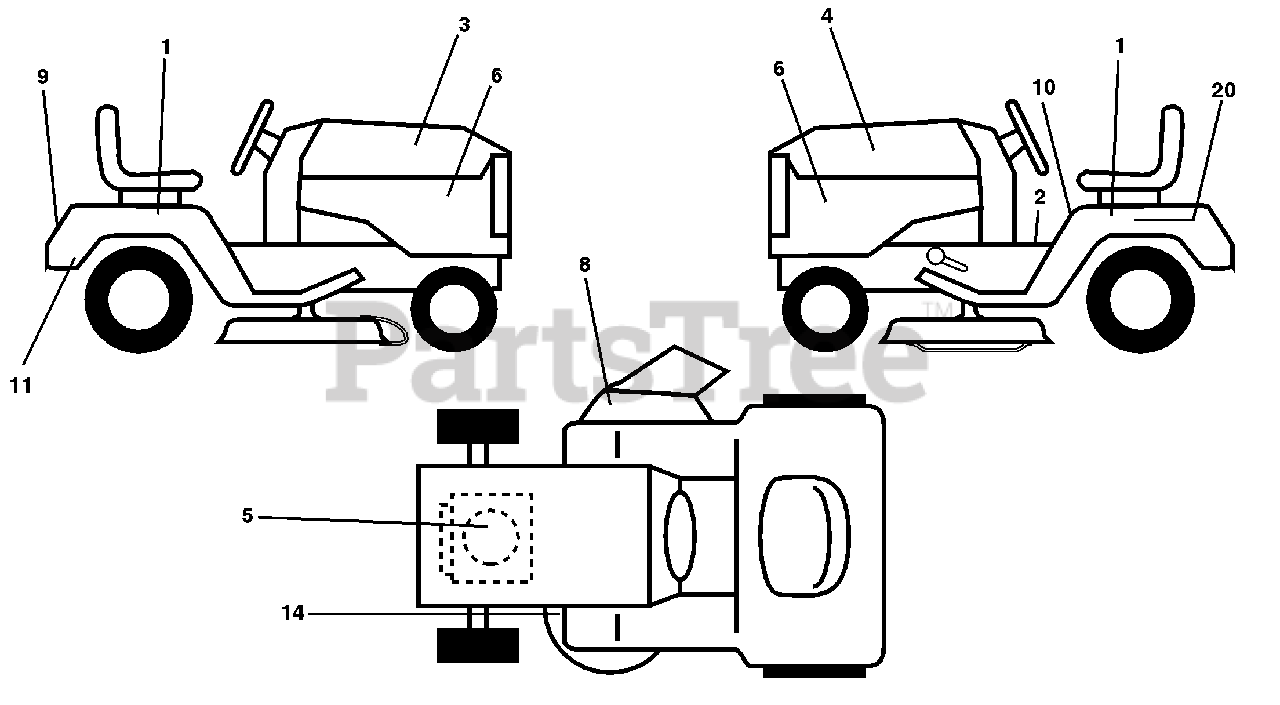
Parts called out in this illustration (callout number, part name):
1	Decal Fender Auto Husq
2	Decal Oper Step Thru Eng/Fr
3	Decal Hood RH
4	Decal Hood LH
5	Decal HP Engine
6	Decal Pnl Side B&S
8	Decal Warning Mult-Language
9	Decal Fender Husq
10	Decal Fender Danger Eng/Fr
11	Decal Drawbar Contrl Mvt
14	Decal V-Belt Schematic
20	Decal Bat Dan/Psn
